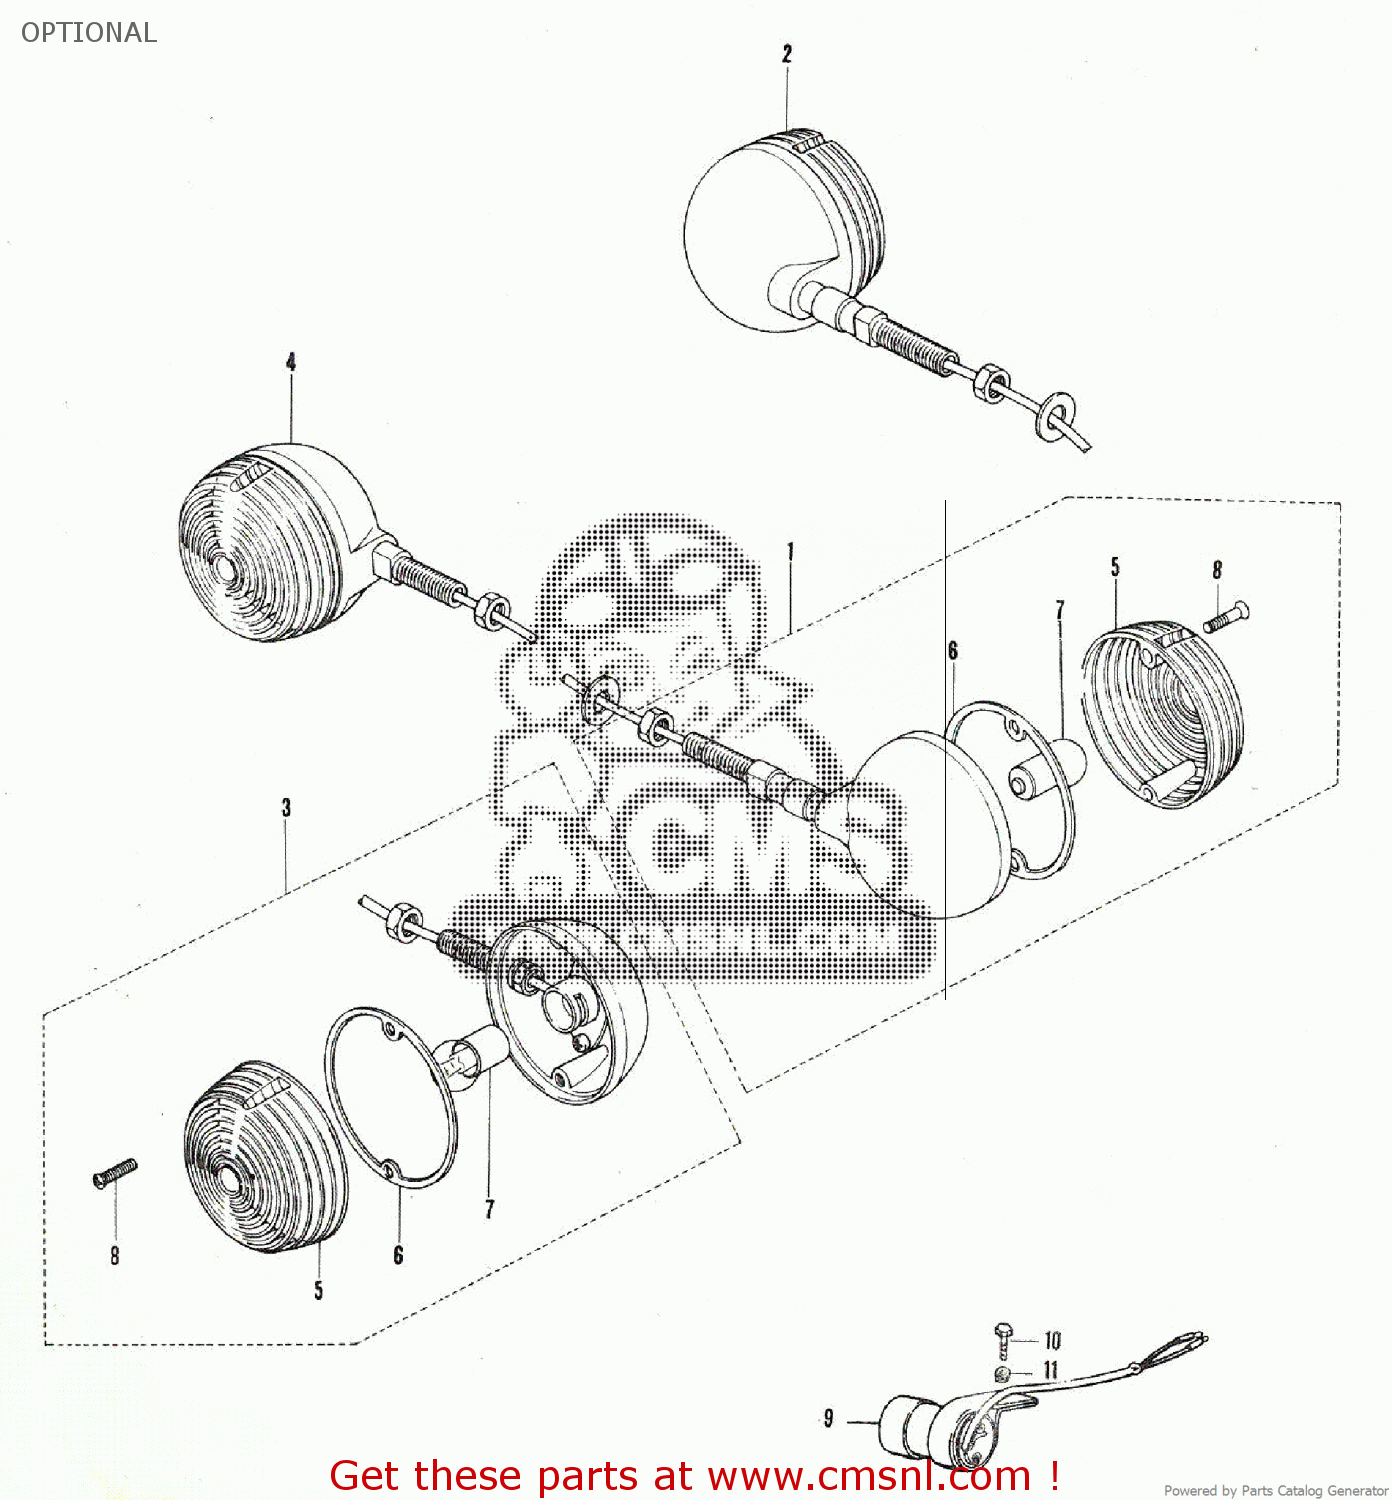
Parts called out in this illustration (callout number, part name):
1	RH FRONT TURN SIGNAL ASS'Y
2	LH FRONT TURN SIGNAL ASS'Y
3	RH REAR TURN SIGNAL ASS'Y
4	LH REAR TURN SIGNAL ASS'Y
5	LENS
6	GASKET (NAS)
7	BULB(6V8W,STANLEY,A4115)
8	SCREW
9	TURN SIGNAL RELAY ASS'Y
10	BOLT
11	LOCK WASHER
